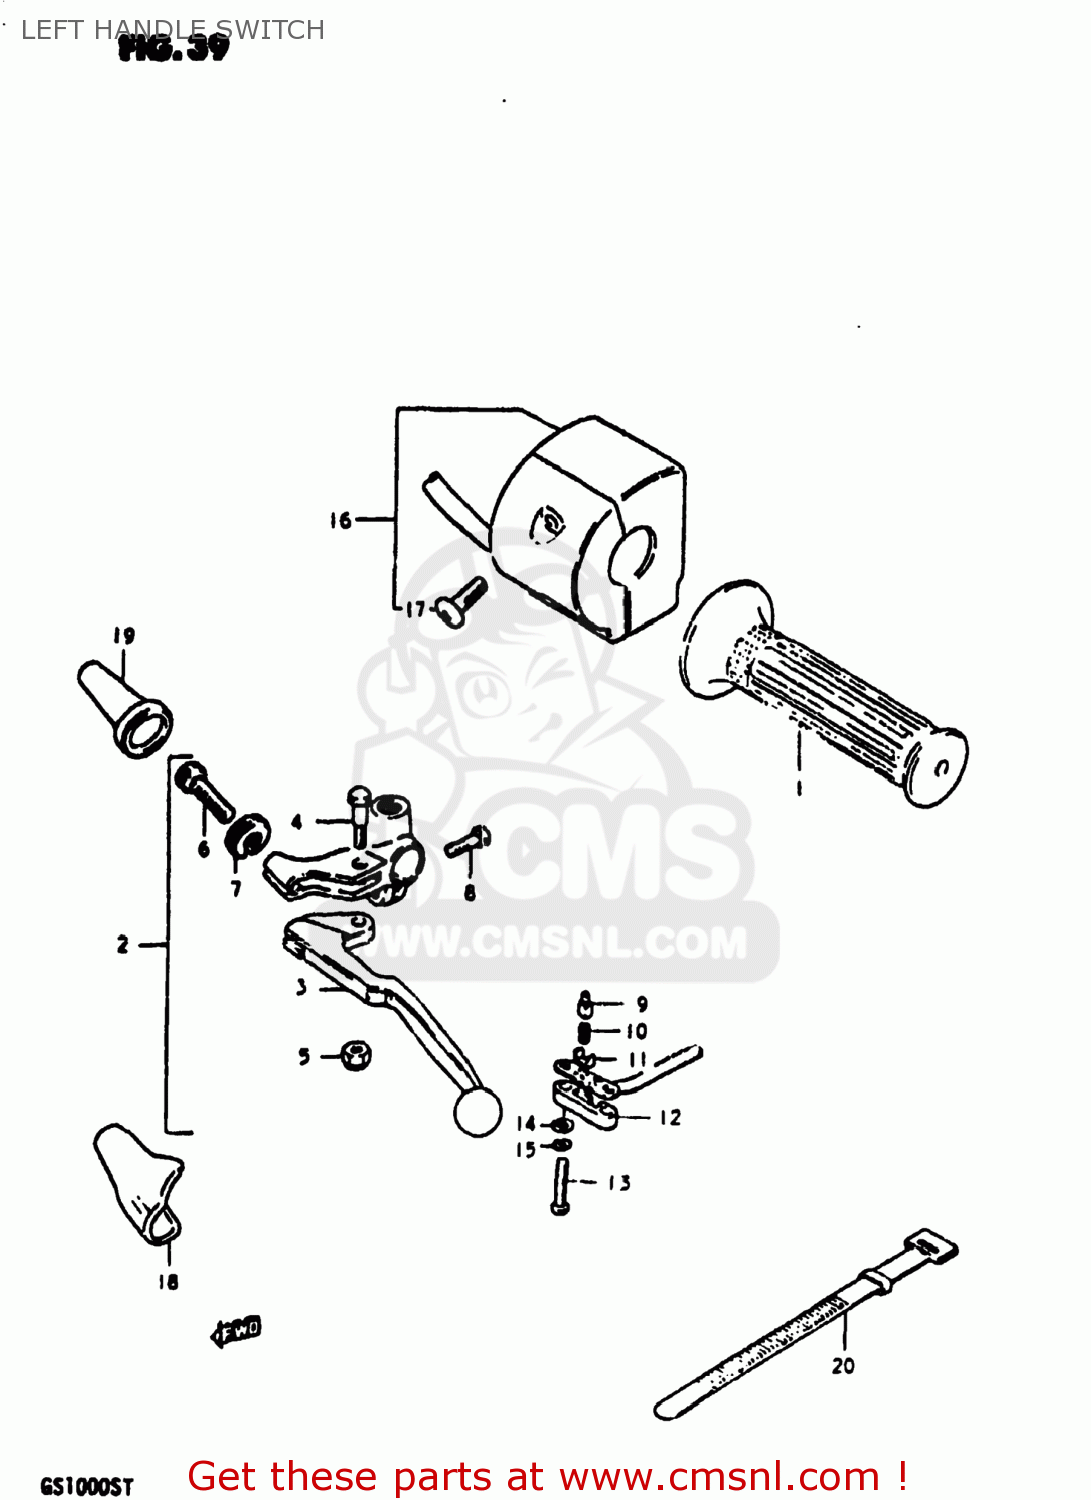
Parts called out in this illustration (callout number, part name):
1	GRIP,LEFT
2	LEVER ASSEMBLY
3	LEVER,CLUTCH
4	BOLT,LEVER
5	NUT 6MM
6	ADJUSTER,CABLE
7	NUT,CABLE ADJUSTER
8	BOLT,CLUTCH LEVER HOLDER
9	HOLDER
10	SPRING
11	PLATE
12	COVER,FR BK TERMINAL BASE
13	SCREW
14	LOCK WASHER
15	WASHER
16	SWITCH ASSEMBLY,HANDLE,LEFT
17	SCREW
18	COVER,CLUTCH LEVER
19	BOOT,CLUTCH CABLE
20	CLAMP(L:120)
